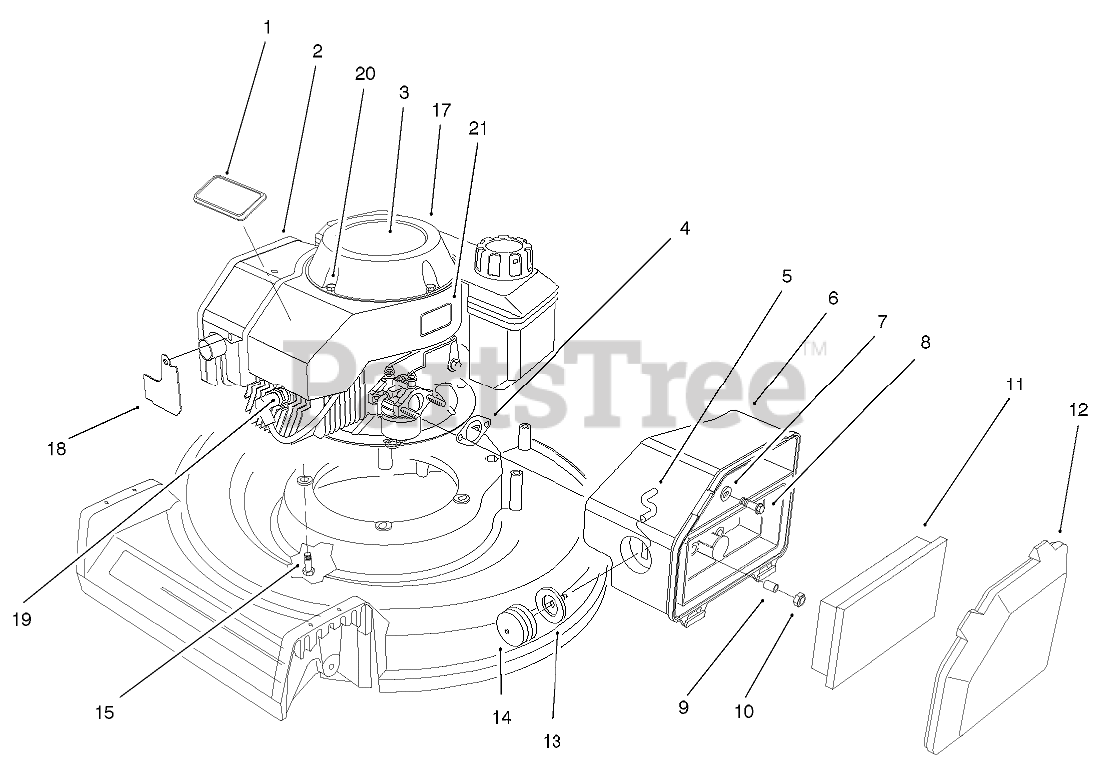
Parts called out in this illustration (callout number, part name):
1	DECAL - PROLINE
2	ENGINE ASM - BBC 2 CYCLE
3	DECAL-2 CYC RECOIL
4	GASKET-AIR CLEANER
5	HOSE-PRIMER
6	BODY-AIR CLEANER
7	WASHER-FLAT
8	SCREW-HH
9	SPACER
11	ELEMENT-AIR CLEANER
12	COVER-AIR CLEANER
13	BODY-PRIMER
14	BULB-PRIMER
15	SCREW-HHF
17	STARTER ASM
18	EXTENSION-MUFFLER GUARD
19	Sparkplug
20	SCREW-HHF
21	DECAL-FUEL, 2 CYCLE
